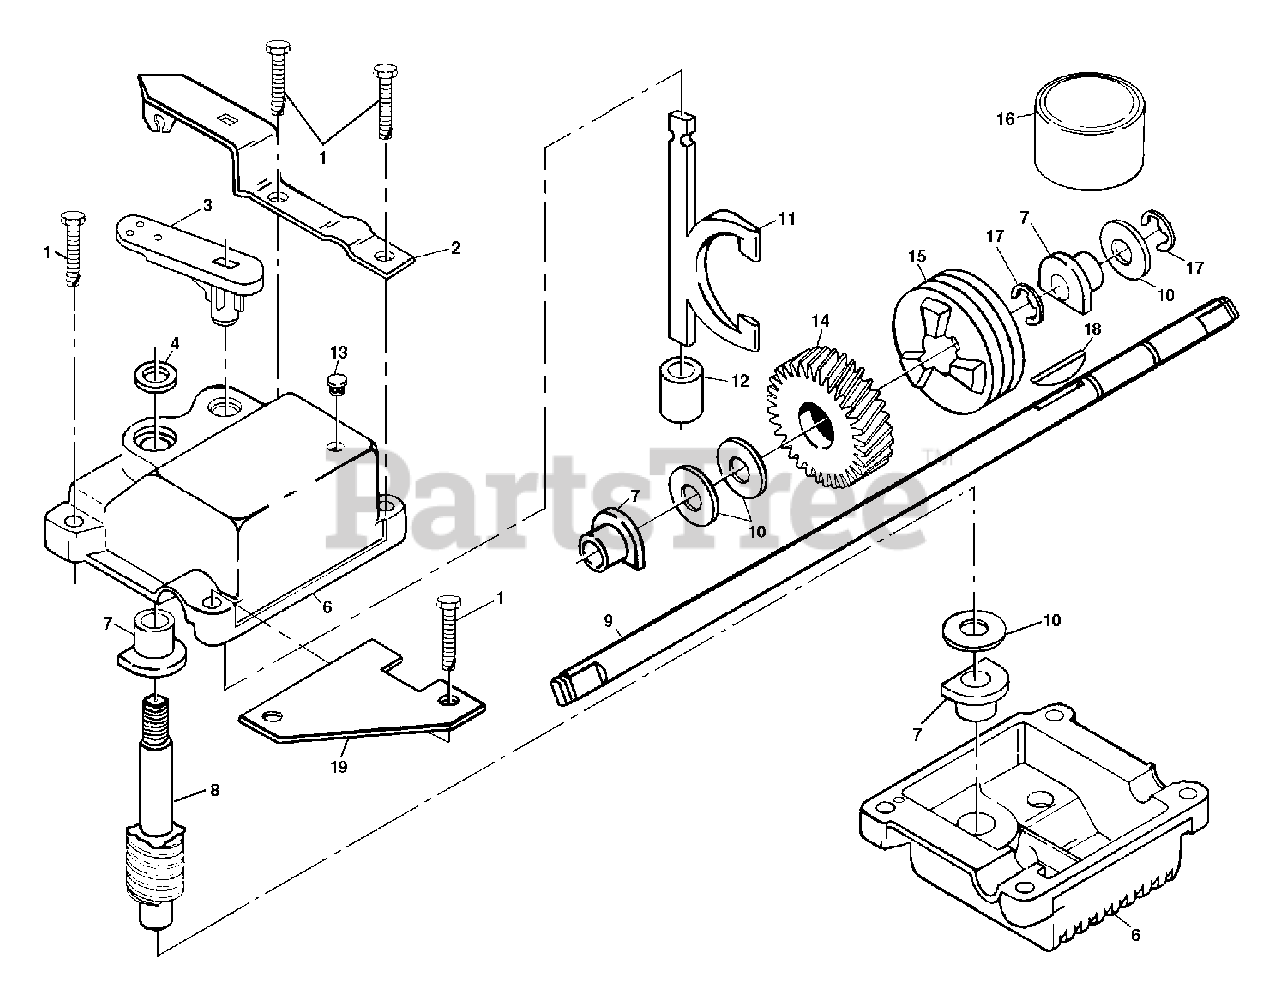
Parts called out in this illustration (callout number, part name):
1	Tapping Screw 1/4-20 x 1-1/4
2	Engagement Bracket
3	Shifter
4	Seal
6	Gear Case Halves Kit
7	Bearing
8	Worm Shaft
9	Drive Shaft
10	Hardened Washer
11	Clutch Yoke
12	Bushing
13	Plug
14	Helical Gear
15	Clutch Jaw
17	E-Ring
18	Hi-Pro Key
19	Spring Bracket
